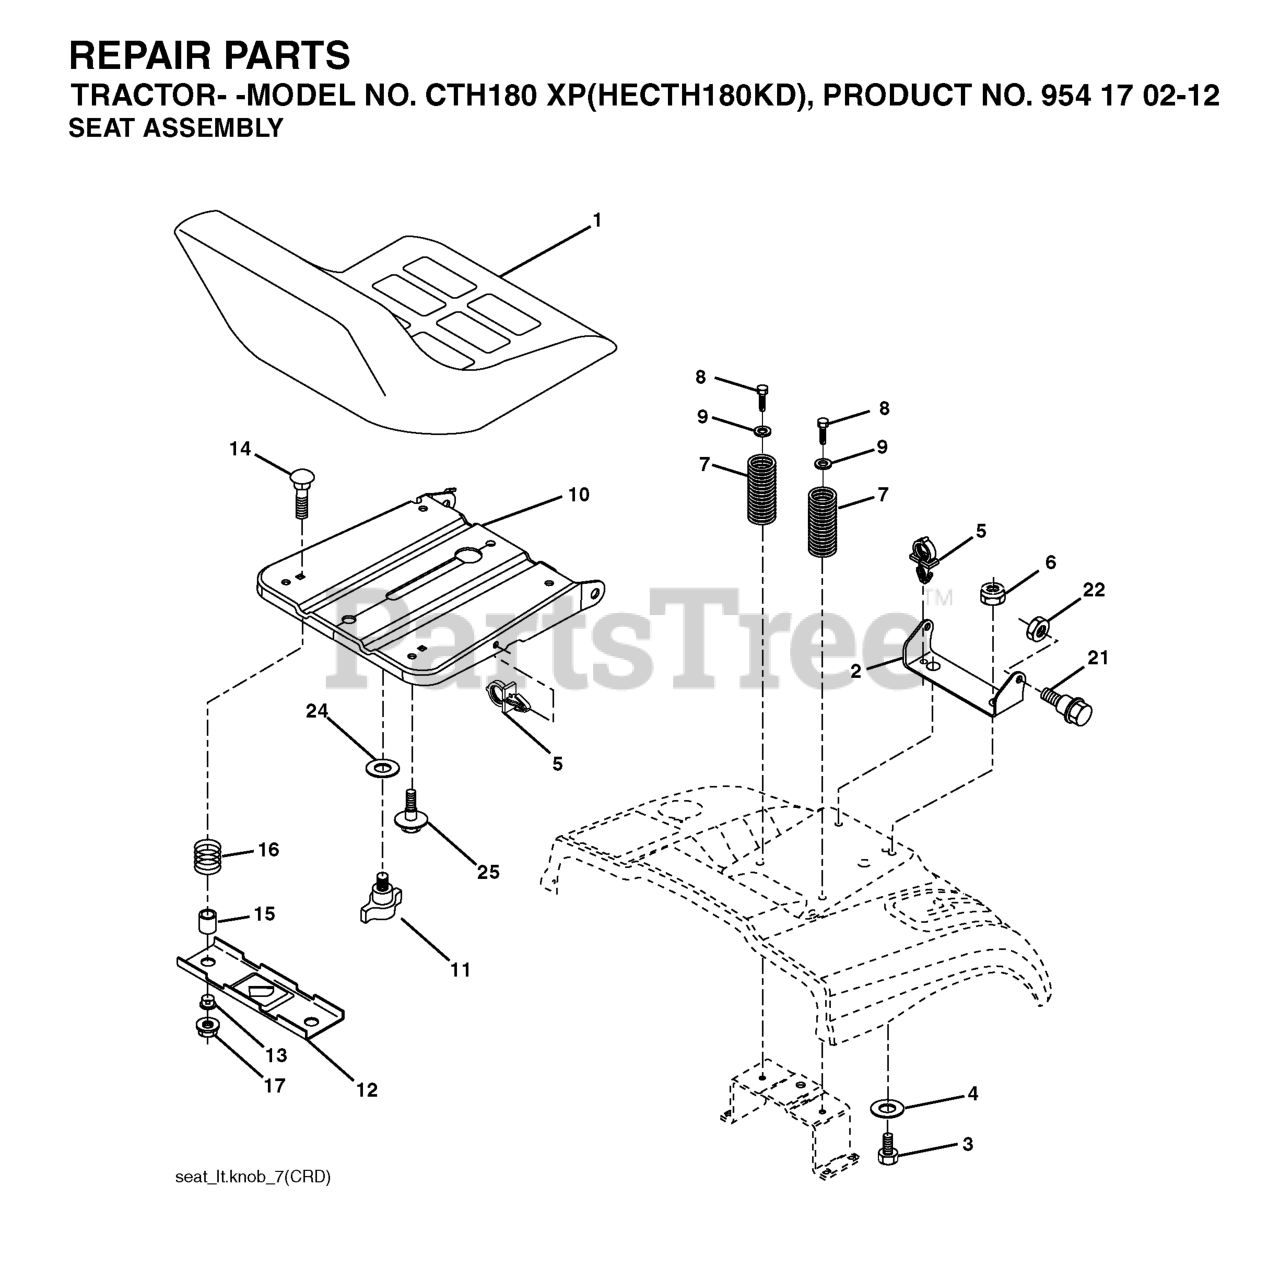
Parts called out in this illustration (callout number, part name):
1	SEAT
2	SEAT PIVOT BRKT
3	BOLT, HEX 3/8-16X1
6	NUT
7	SPRING COMPRESSION
8	SCREW 3/8-16X1
9	WASHER
10	PAN SEAT
11	KNOB.SEAT.ADJ.WINGNUT
12	BRKT SWITCH
14	BOLT.ROUND.HEAD.SQUARE.NECK
15	SPACER SPLIT
16	SPRING COMPRESSED
17	NUT T
21	BOLT.SHOULDER.5/16-18
22	NUT.71038.31-18.HEX.NYLOCK
25	BOLT,SHOULD
